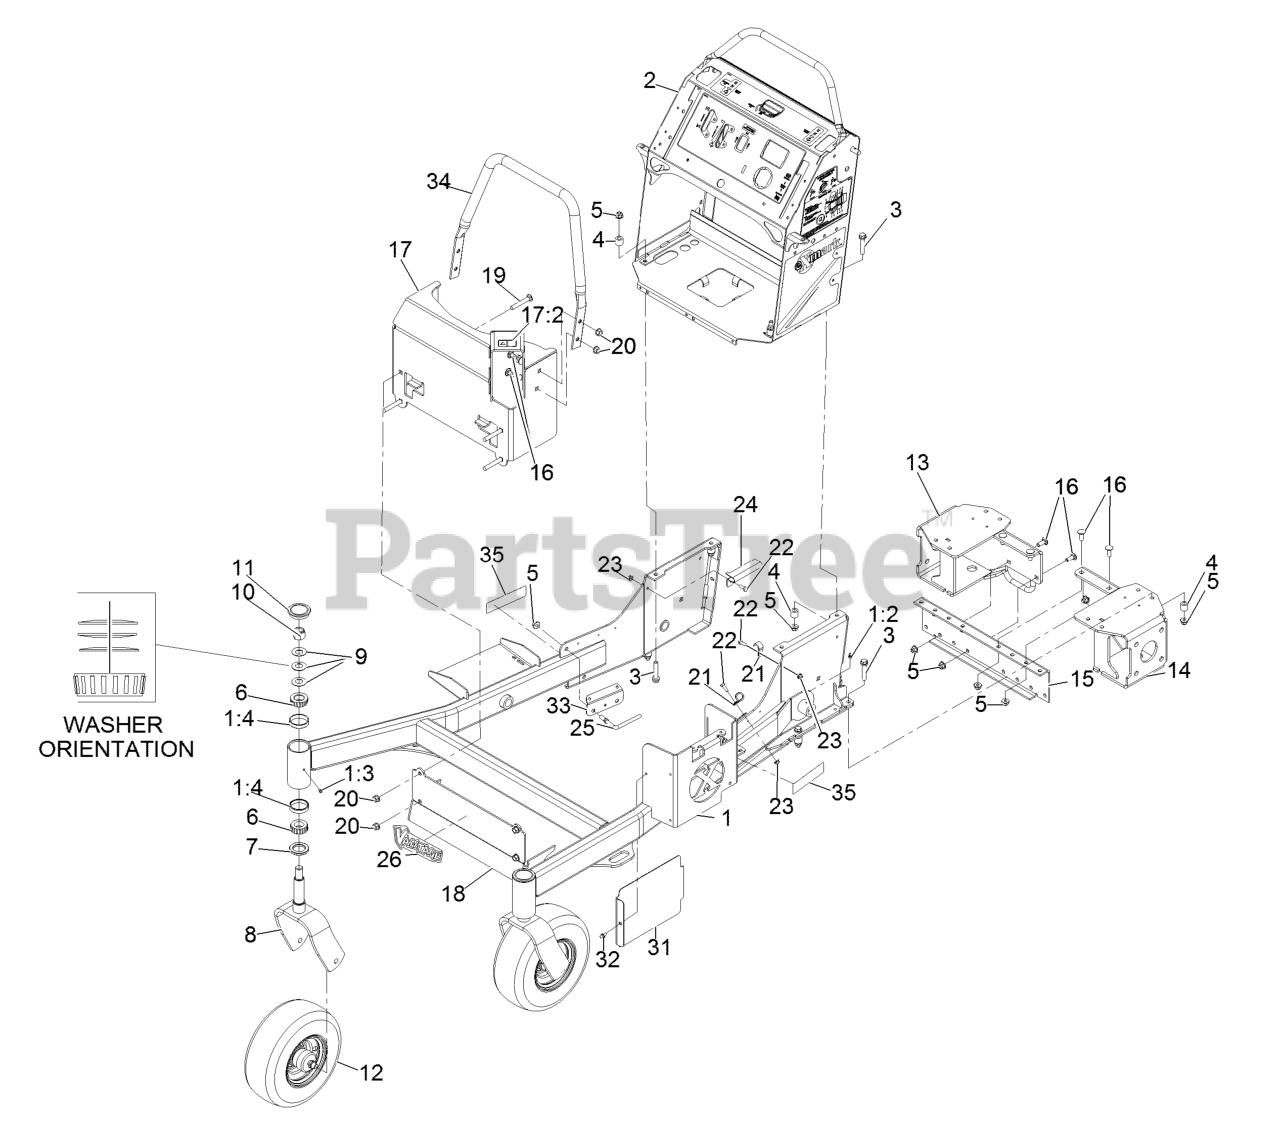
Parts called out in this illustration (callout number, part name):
1	FRONT FRAME ASM
1:2	FITTING-GREASE
1:4	CUP-BEARING
2	CONTROL TOWER ASM
3	SCREW-HHF
5	NUT-HF, NI
6	Cone-Bearing Tapered Roller
7	SEAL-GREASE
8	FORK-CASTER
9	WASHER-BELLVILLE
10	NUT-LOCK, NI
11	CAP-GREASE
12	WHEEL/TIRE AND BEARING AS
13	RH MOTOR MOUNT ASM
14	LH MOTOR MOUNT ASM
15	MOUNT-MOTOR, CENTER
16	SCREW-CARR
17:2	DECAL-WARNING
18	PANEL-GUARD
19	SCREW-CARR
21	CLAMP-CABLE
22	SCREW-HH
24	BRACKET-HOSE, FUEL (DOUBL
25	GUIDE-HOSE, SUPPORT
26	DECAL-VANTAGE LOGO
31	SHIELD-HEAT, TALL
32	SCREW-HWH
33	GUARD-HOSE
34	TUBE-GUARD
35	DECAL-S-SERIES
